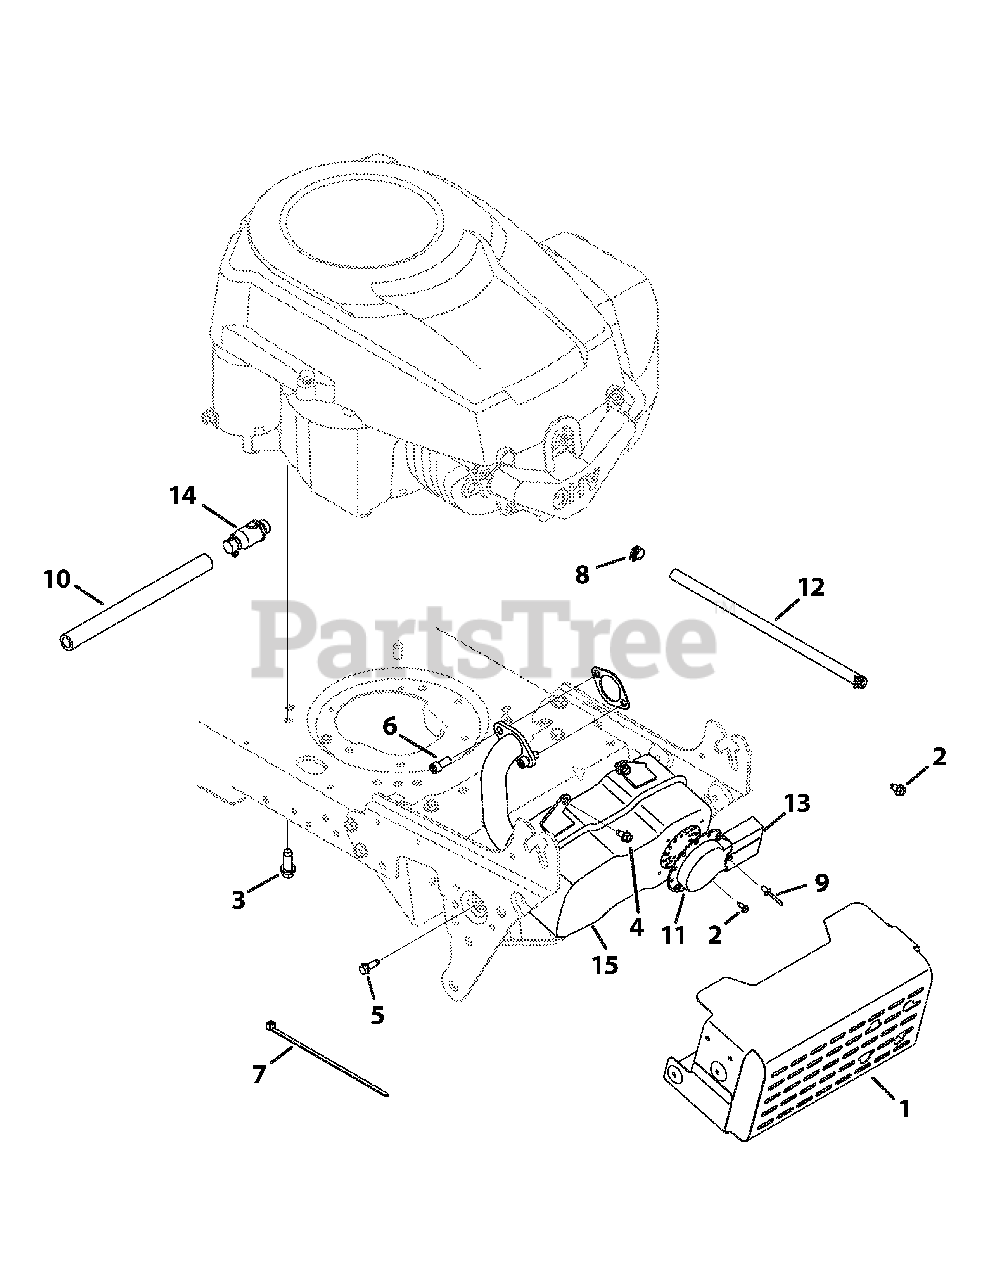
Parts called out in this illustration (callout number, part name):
1	Muffler Shield Assembly with Weld
2	Screw, 8-18 x .500
3	Screw, 3/8-16 x 1.0
4	Screw, 1/4-20 x .500
5	Screw, 1/4-20 x .750
6	Socket Screw, 5/16-18 x .750
7	Cable Tie
8	Clamp Hose, .490 diameter
9	Rivet, .188 x .300
10	Oil Drain, Extension Hose
11	Muffler Deflector
12	Fuel Hose, Low Permeation
13	Muffler Deflector Long
14	Oil Drain
15	Muffler
